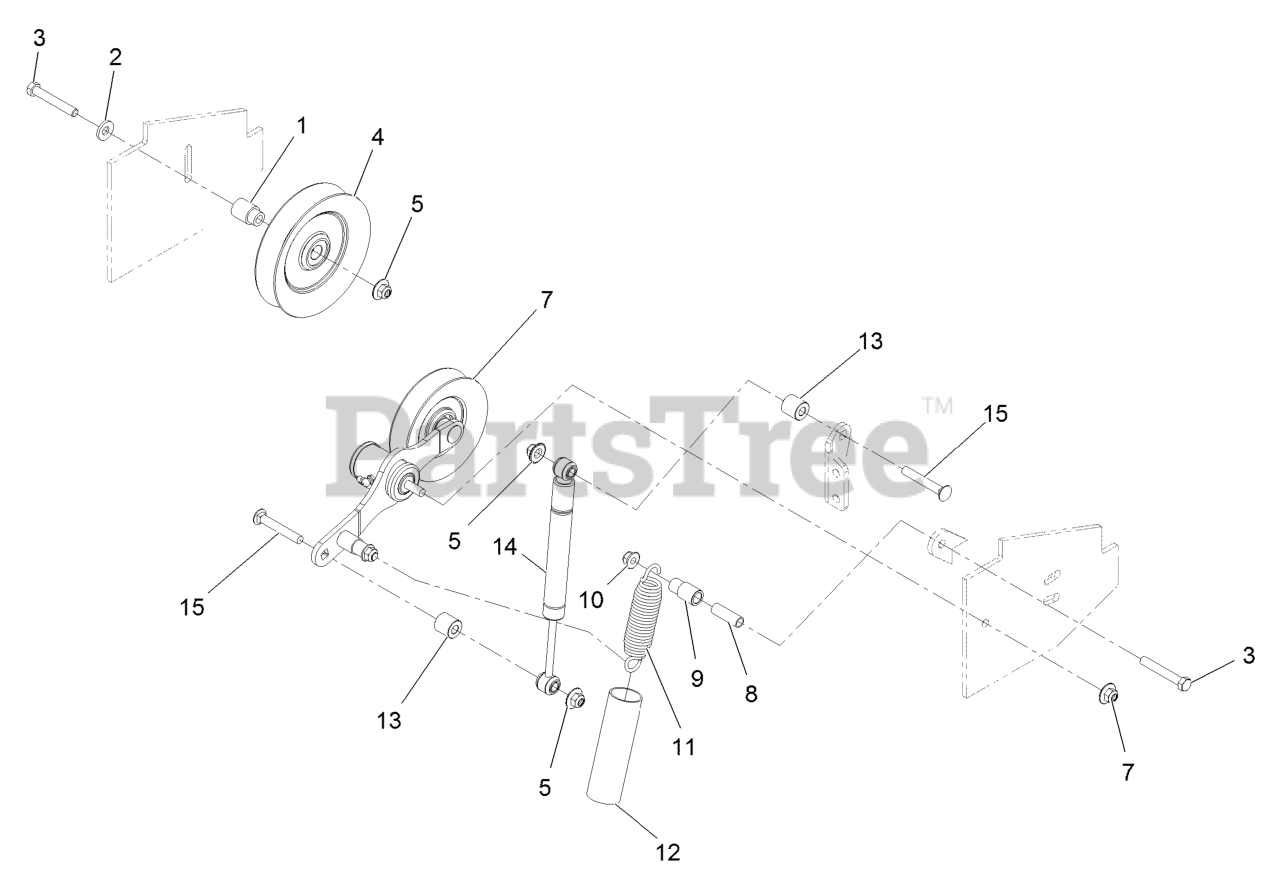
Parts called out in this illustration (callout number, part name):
1	BUSHING-IDLER
2	WASHER-BELLEVILLE
3	BOLT-CARR
4	PULLEY-IDLER
5	Nut-Nyloc 3/8-16 Flg
7	ASM-TTNR ARM W/PULLEY
9	BUSHING,PLASTIC
10	NUT-HF, NI
11	SPRING-EXTENSION
12	DAMPENER,SPRING
13	SPACER-.39IDX.88ODX.88L
14	DAMPER-MULE BELT DRIVE
15	SCREW-CARR
